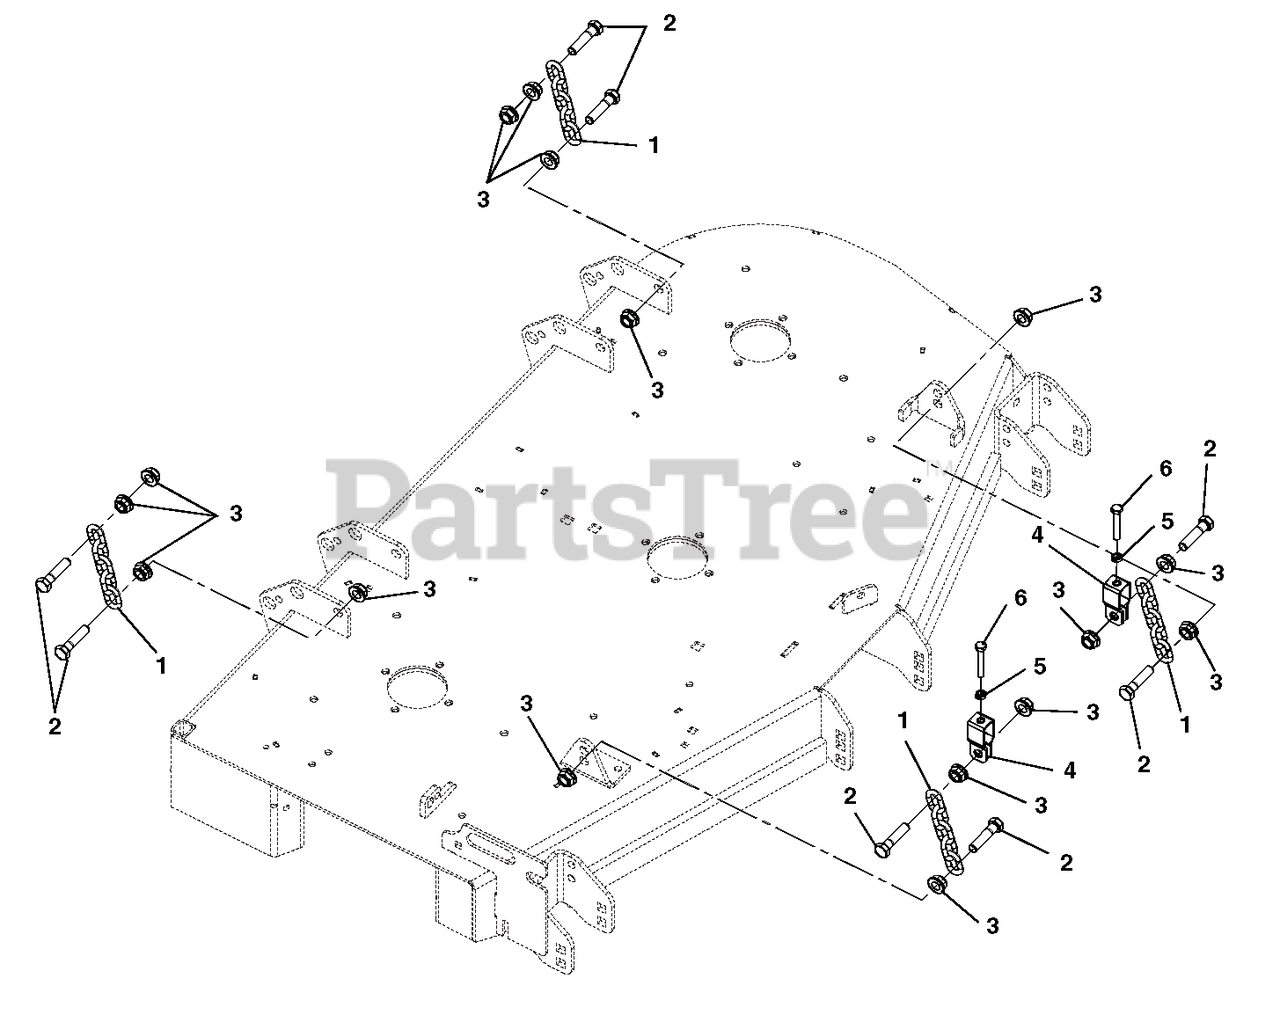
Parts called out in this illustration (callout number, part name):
1	CHAIN, LINK
2	BLT, HEX M12-1.75X50 CLS8.8 YZ
3	NUT-SPNLK-FLG M12-1.75 YZ
4	BRKT, DECK LEVELING
5	NUT- JAM .312-18 YWZC
6	BLT-HEX .312-18X2.00 FTH GR5YZ
